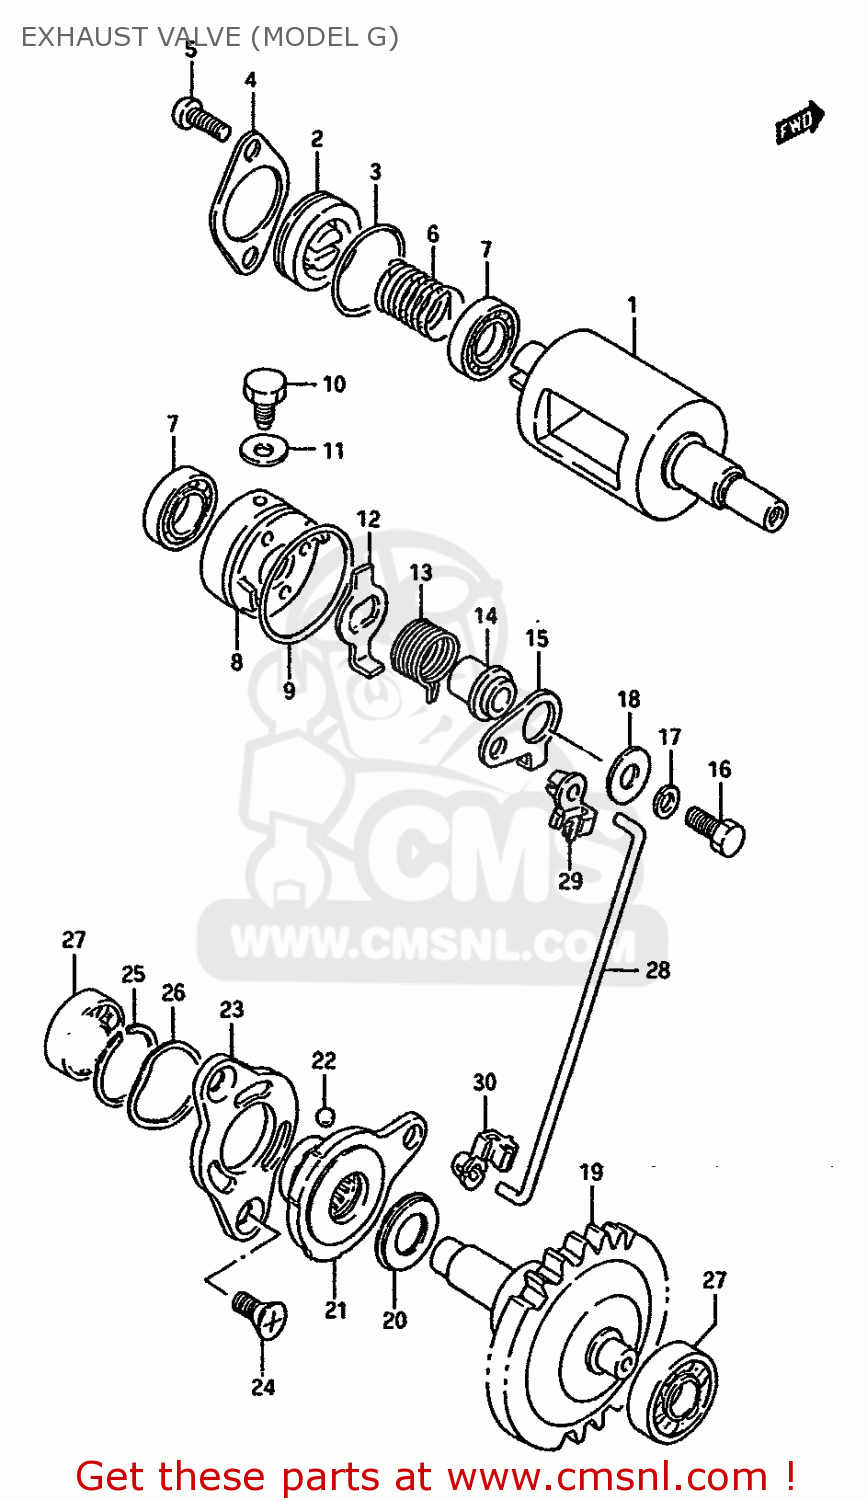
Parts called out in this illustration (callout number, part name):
1	VALVE,EXHAUST
2	CAP,EXHAUST VALVE
3	O RING(D:1.9,ID:22.6)
4	RETAINER,EXHAUST VALVE
5	SCREW
6	SPRING
7	BEARING
8	HOLDER,EXHAUST VALVE
9	O RING(D:2.4,ID:27.7)
10	BOLT
11	GASKET(6.2X11X1).2 (NAS)
12	LEVER,EXHAUST VALVE NO
13	SPRING
14	SPACER,EXHAUST VALVE
15	LEVER,EXHAUST VALVE NO.1
16	BOLT
17	LOCK WASHER
18	WASHER (5.5X16X1.2)
19	GOVERNOR ASSEMBLY,EXHAUST
20	BEARING(10X22X2.8)
21	ACTUATOR,EXHAUST VALVE
22	BALL
23	STARTER,EXHAUST VALVE ACTUATOR
24	SCREW 5X12
25	CIRCLIP
26	WASHER
27	BEARING(8X22X7)
28	ROD,EXHAUST VALVE
29	BUSH,EXHAUST VALVE ROD NO.1
30	BUSH,EXHAUST VALVE ROD NO.2
